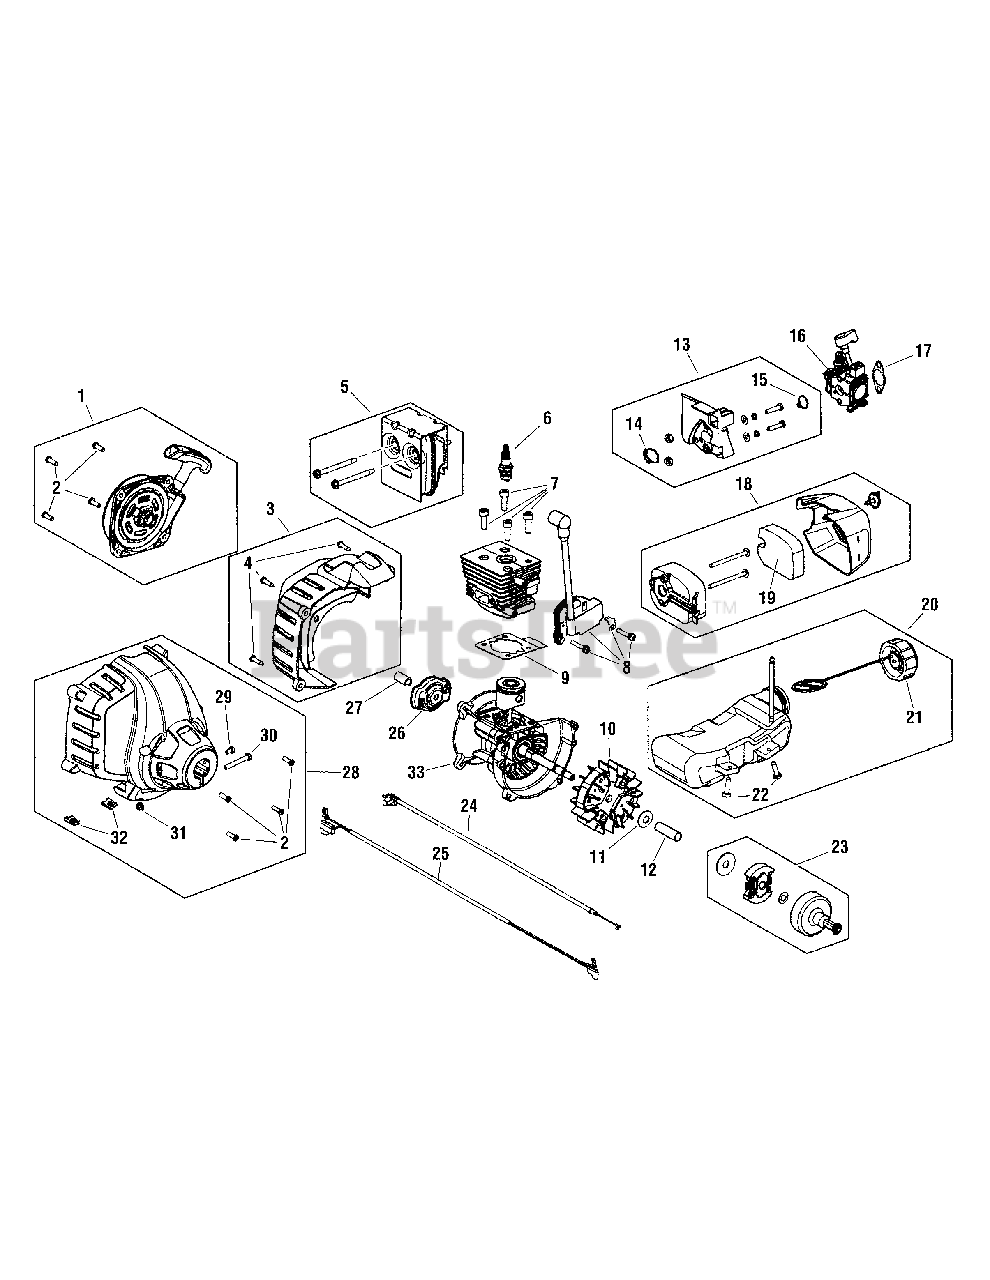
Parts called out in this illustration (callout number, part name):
1	ASSEMBLY, Starter
2	SCREW, Starter
3	COVER, Rear Engine
4	SCREW, Cover
5	Muffler Assembly
6	Spark Plug
7	BOLT, Cylinder
8	ASSEMBLY, Module
9	GASKET, Cylinder
10	ASSEMBLY, Flywheel
13	Insulator Assembly
14	O-RING, Insulator
15	O-RING, Carburetor
16	CARBURETOR
17	Carburetor Gasket
18	ASSEMBLY, Air Cleaner
19	FILTER, Air Cleaner
20	ASSEMBLY, Fuel Tank
21	CAP, Fuel Tank
22	SCREW, Fuel Tank
23	ASSEMBLY, Clutch
24	CABLE, Throttle
25	WIRES, Lead
26	ASSEMBLY, Pawl
27	ADAPTER
28	ASSEMBLY, Clutch Cover
29	SCREW, Anti-Rotation
30	SCREW, Clamp
31	NUT, Clamp
32	NUT, U-Shaped
